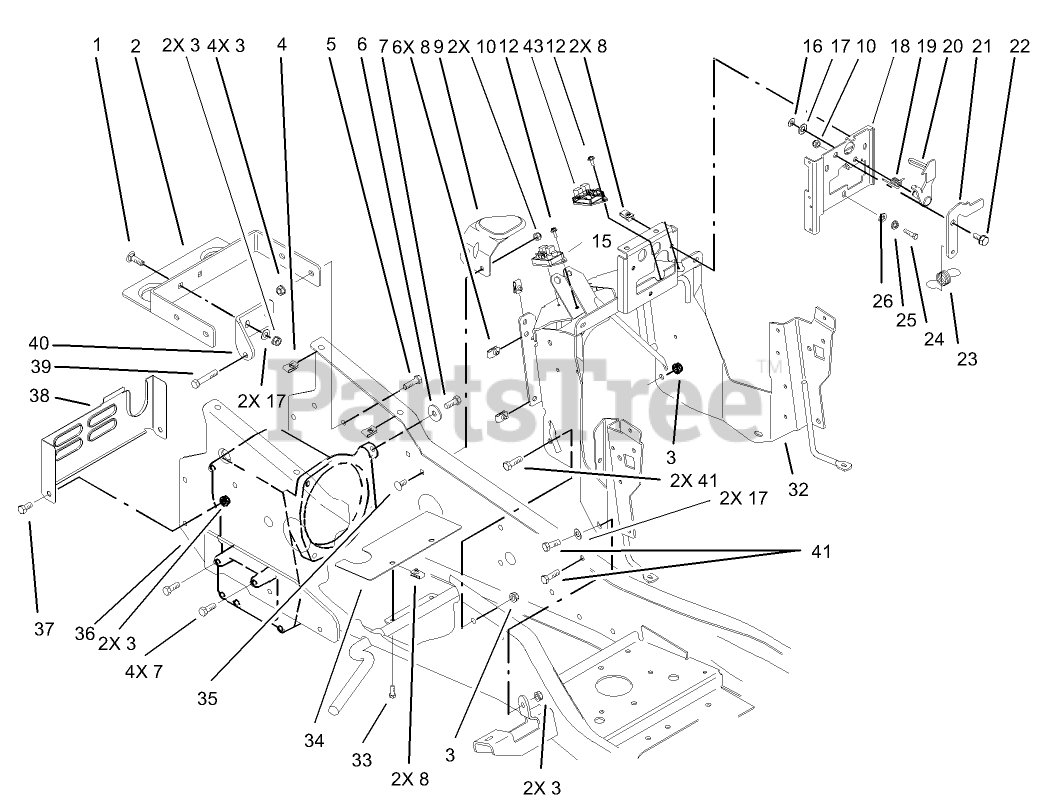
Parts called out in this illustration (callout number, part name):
1	BOLT-CARR
2	SUPPORT-GAS TANK
3	NUT-LOCK, NI
4	NUT-U
5	SCREW-HH
6	WASHER
7	SCREW-HH, LOCK
9	SUPPORT-TANK, FUEL
10	NUT-LOCK, NI
12	SCREW-HWH
15	MODULE-CRUISE
16	RING-RETAINING
17	WASHER-FLAT
18	BRACKET-LATCH
19	SPRING-LEVER, LATCH
21	LATCH-LEVER, TENSION
22	BOLT-SHOULDER,HFH
23	SPRING-LEVER, LATCH
24	SCREW-HH
25	WASHER-LOCK
26	WASHER-FLAT
32	TOWER ASM
33	SCREW-HH
34	BAFFLE-FAN
37	SCREW-HH
38	COVER-REAR
39	SCREW-HH W/LOCTITE
40	STRAP-TORQUE
41	SCREW-HH
43	MODULE-CLUTCH
